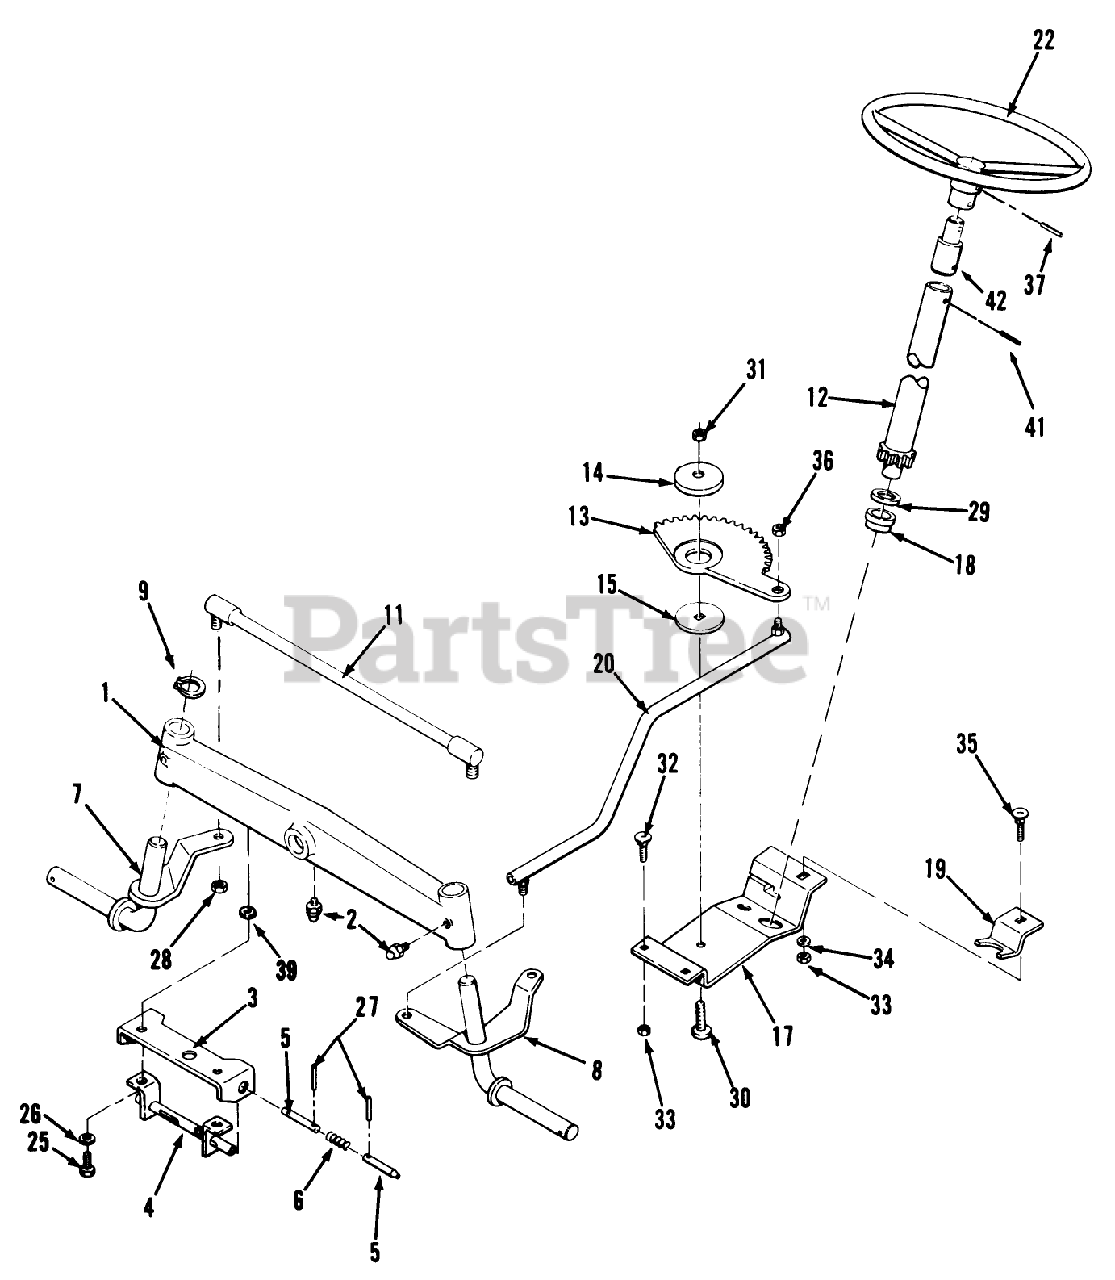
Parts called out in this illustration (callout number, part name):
2	FITTING-GREASE
9	RING-RETAINING
14	BUSHING
15	WASHER-BEARING
18	BEARING-WHEEL
25	SCREW-HH
26	WASHER-LOCK
27	PIN-SPRING
29	WASHER
30	SCREW-CARR
31	NUT-HEX
32	BOLT-CARR
33	NUT-LOCK, NI
34	WASHER-PLAIN
35	BOLT-CARR
39	WASHER
41	PIN-ROLL
42	SHAFT-COUPLER
